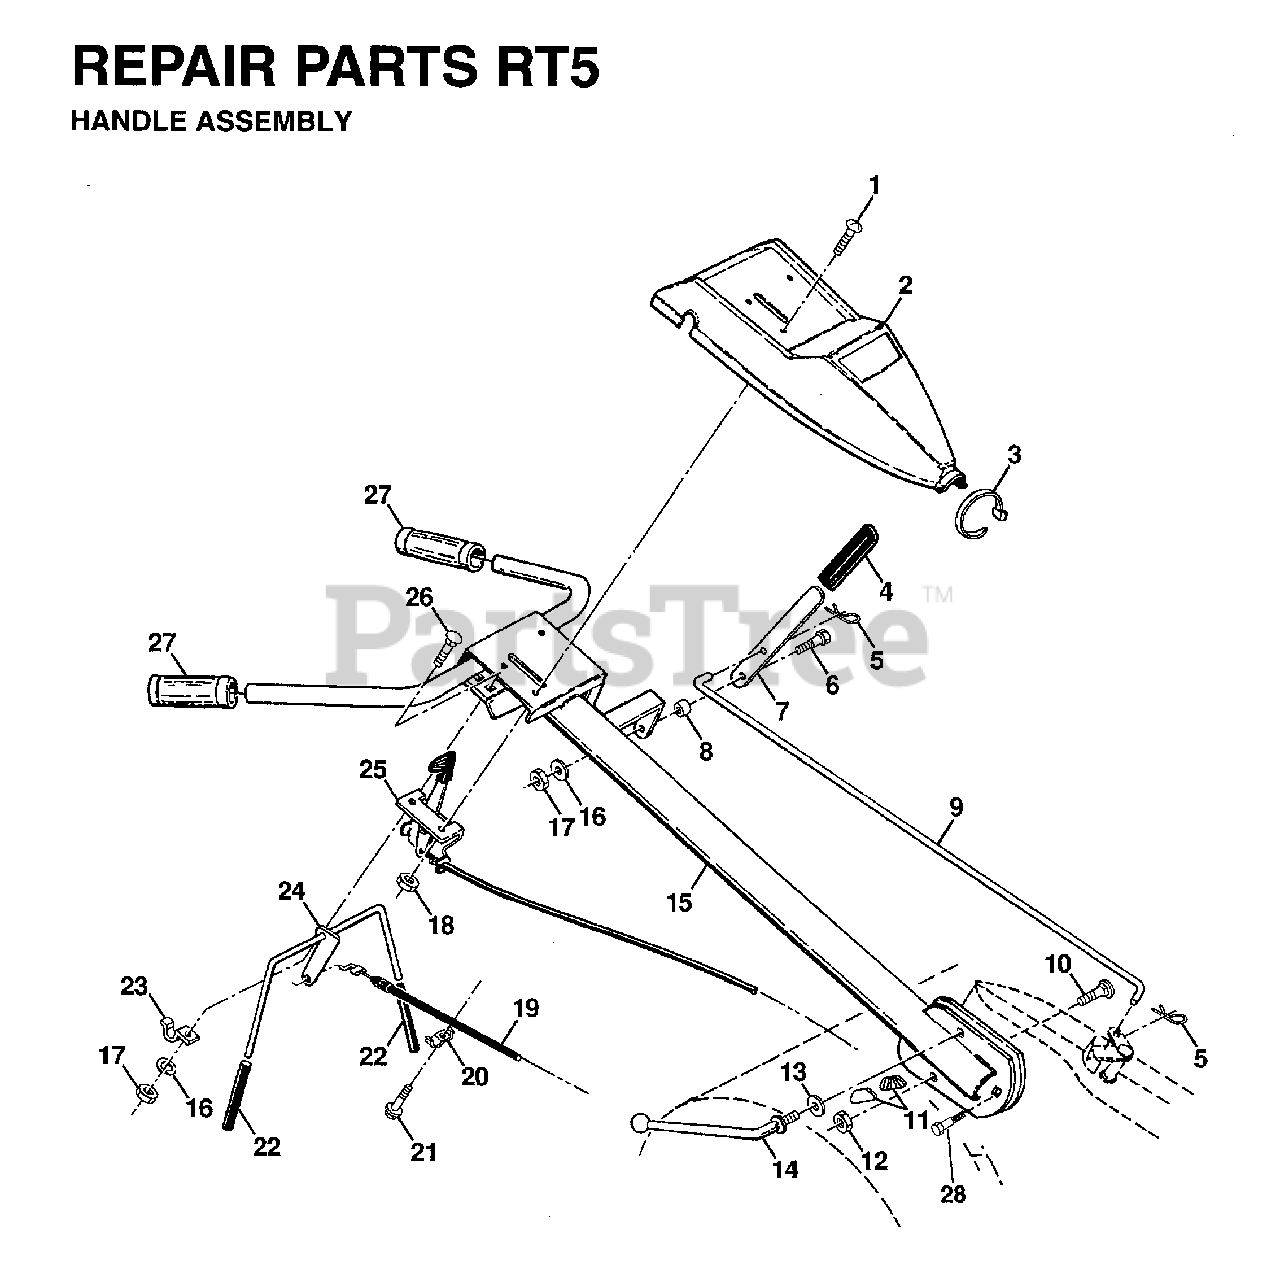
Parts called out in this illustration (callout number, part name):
3	GRIPS (2EACH)
5	LOCKNUT
6	WASHER - 15X7.3X1.6
7	WASHER
9	BOLT
10	LOCKWASHER
12	LOCKNUT
13	BOLT
17	KNOB T (3/8 HOLE)
21	RETAINING RING
25	WASHER
26	COTTER PIN
27	COTTER PIN
28	WASHER
